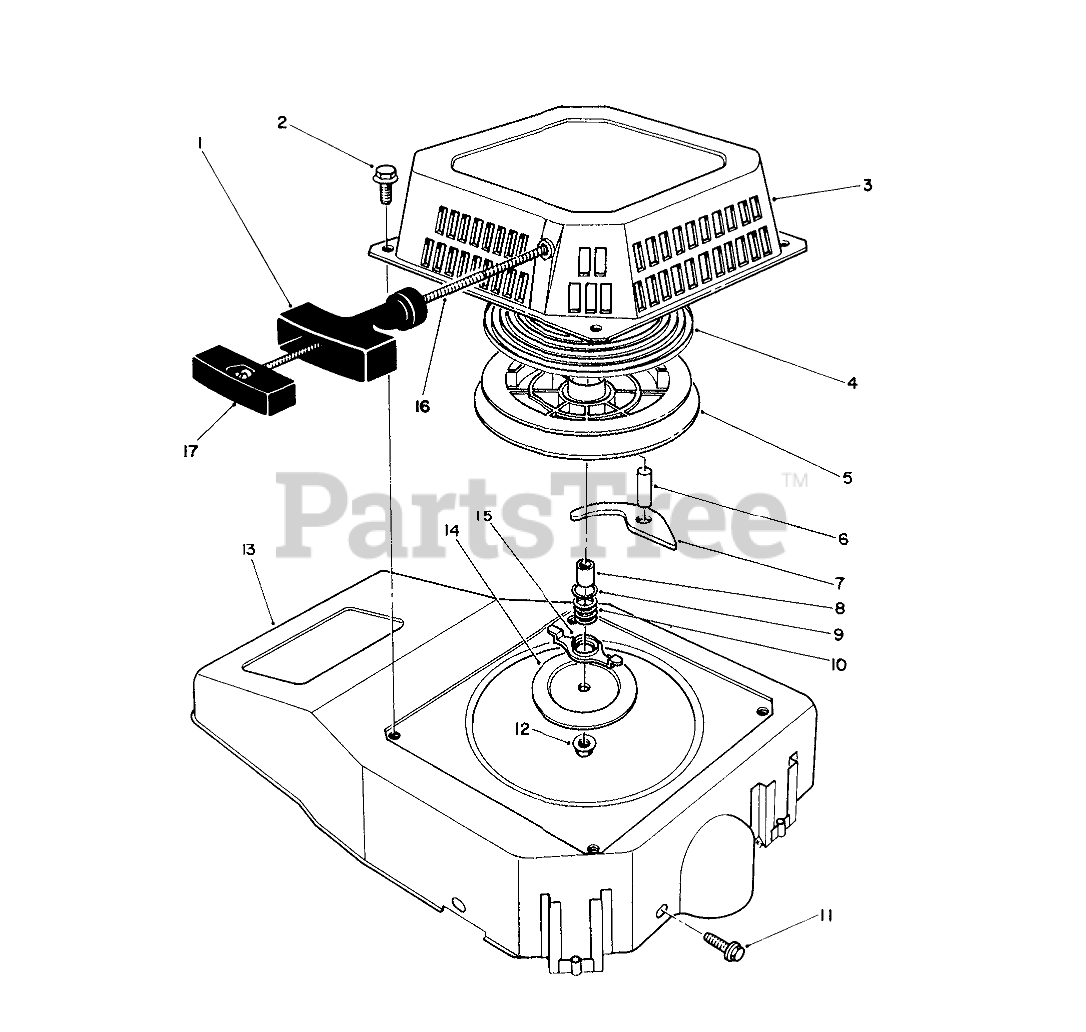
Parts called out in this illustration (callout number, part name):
1	HANDLE
2	SCREW-HHF
3	Case-Recoil
4	SPRING
8	Spacer
9	WASHER
10	Spring-Friction
13	SHROUD
14	PLATE
15	Guide-Paw
16	ROPE-STARTER
17	RETAINER HANDLE
